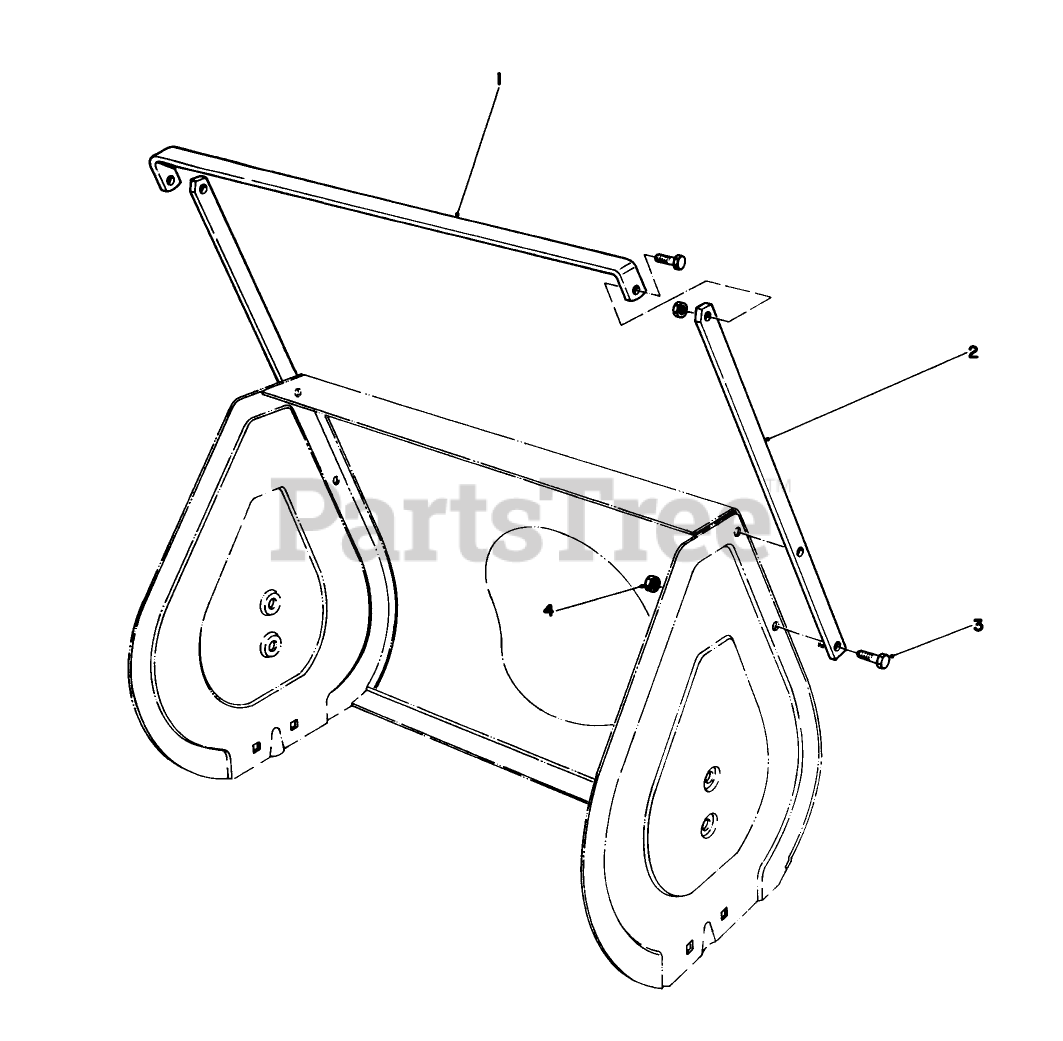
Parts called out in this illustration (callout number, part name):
1	Cutter Deck
2	Drift Breaker-Side
3	SCREW-HH
4	NUT-LOCK, NI
